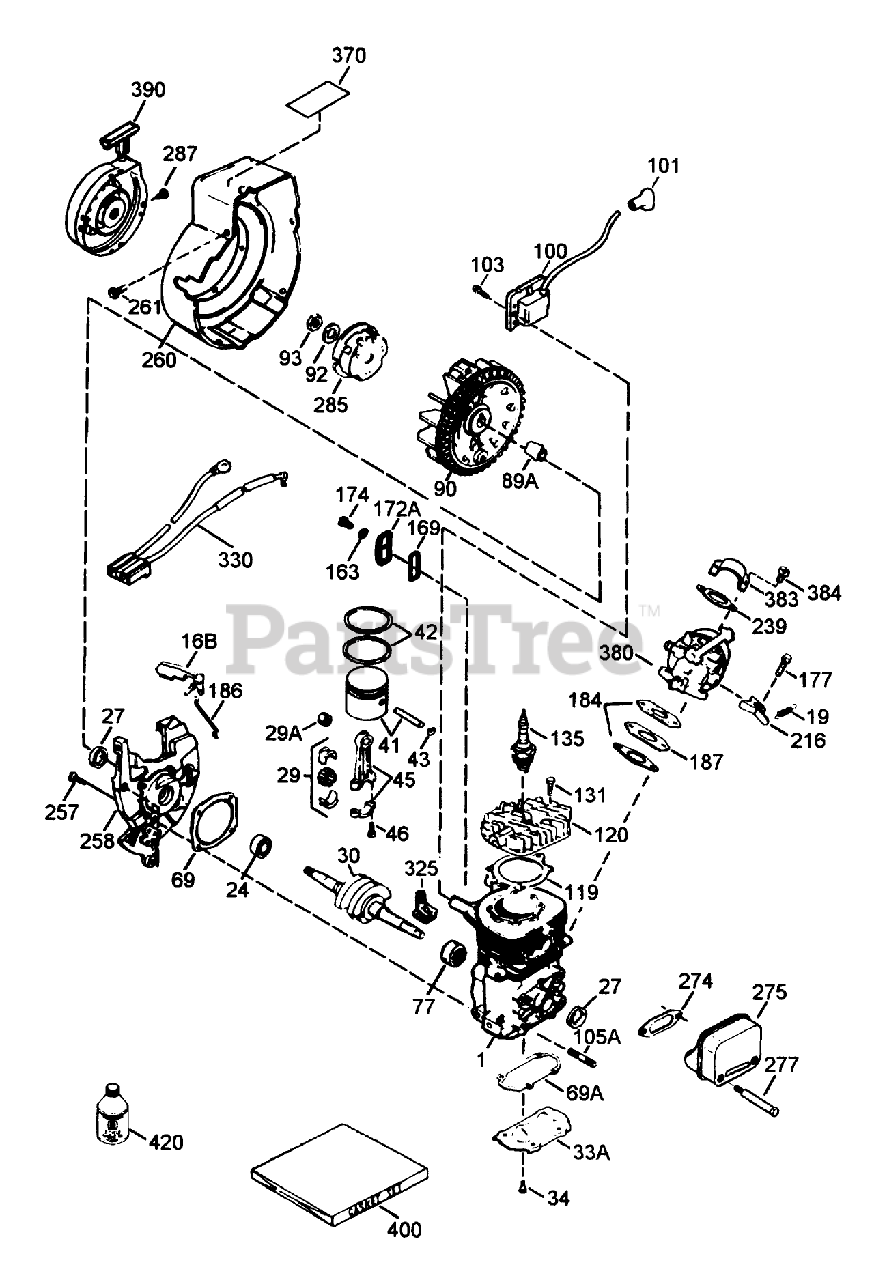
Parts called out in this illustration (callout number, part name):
1	Block Ass-y Cylinder (Order short block if replacement is required)
16B	Vane-Air
19	Spring-Extention
24	Bearing-Ball
27	Seal-Oil
29	Needle Bearing and Liner Set (37 Needles)
29A	Bearing-Cartridge
30	Crankshaft
33A	Plate-Cover
34	Screw (T-25, 10-24 x 1/2)
41	Piston (Incl. Ref. #43)
42	Ring Set
43	Ring-Retaning
45	Rod Assy.-Connecting (Incl. Ref. #3, 3A 3B)
46	Bolt-Rod, Connecting
69	Gasket-Cover, Cylinder
69A	Gasket-Plate, Cover
77	Bearing-Cartridge
89A	Blade (20 inch)
90	CARB BODY S
92	Washer-Belleville
93	Nut-Flywheel
100	Solid State
101	Cover-Spark Plug
103	Screw
119	Gasket-Head, Cylinder
120	Head-Cylinder
131	Screw (T-30, 1/4-20 x 3/4)
135	Spark Plug-Resistor (R C J 8Y)
163	Washer
169	Cover-Compression, Release
172A	Cover-Release, Compression
174	Screw (T-25, 10-24 x 1/2)
177	Screw (5/32 Allen, 1/4-20 x 1)
184	Gasket-Carburetor
186	Governor-Link
187	Spacer
216	Lever-Adjusting, Rpm
239	2060A77 WIZARD ROTA
257	Screw (T-30, 1/4-20 x 5/8)
258	Base Ass-y-Blower Housing (Incl Ref. #20)
260	Housing-Blower
261	Screw (1/4-20 x 1/2)
274	Gasket-Exhaust
275	Muffler (Incl. Ref. #274 277)
277	Screw (1/4-20 x 2-3/4)
285	Cup-Starter
287	Screw (8-32 x 21/64)
325A	Clip-Wire
330	Harness-Wire
370	Decal-Warning
380	Carburetor (Incl. Ref. #184A)
383	Baffle-Carburetor
384	Screw
390	Rewind Starter
400	Gasket Set
422	2-Cycle Oil (8oz)
